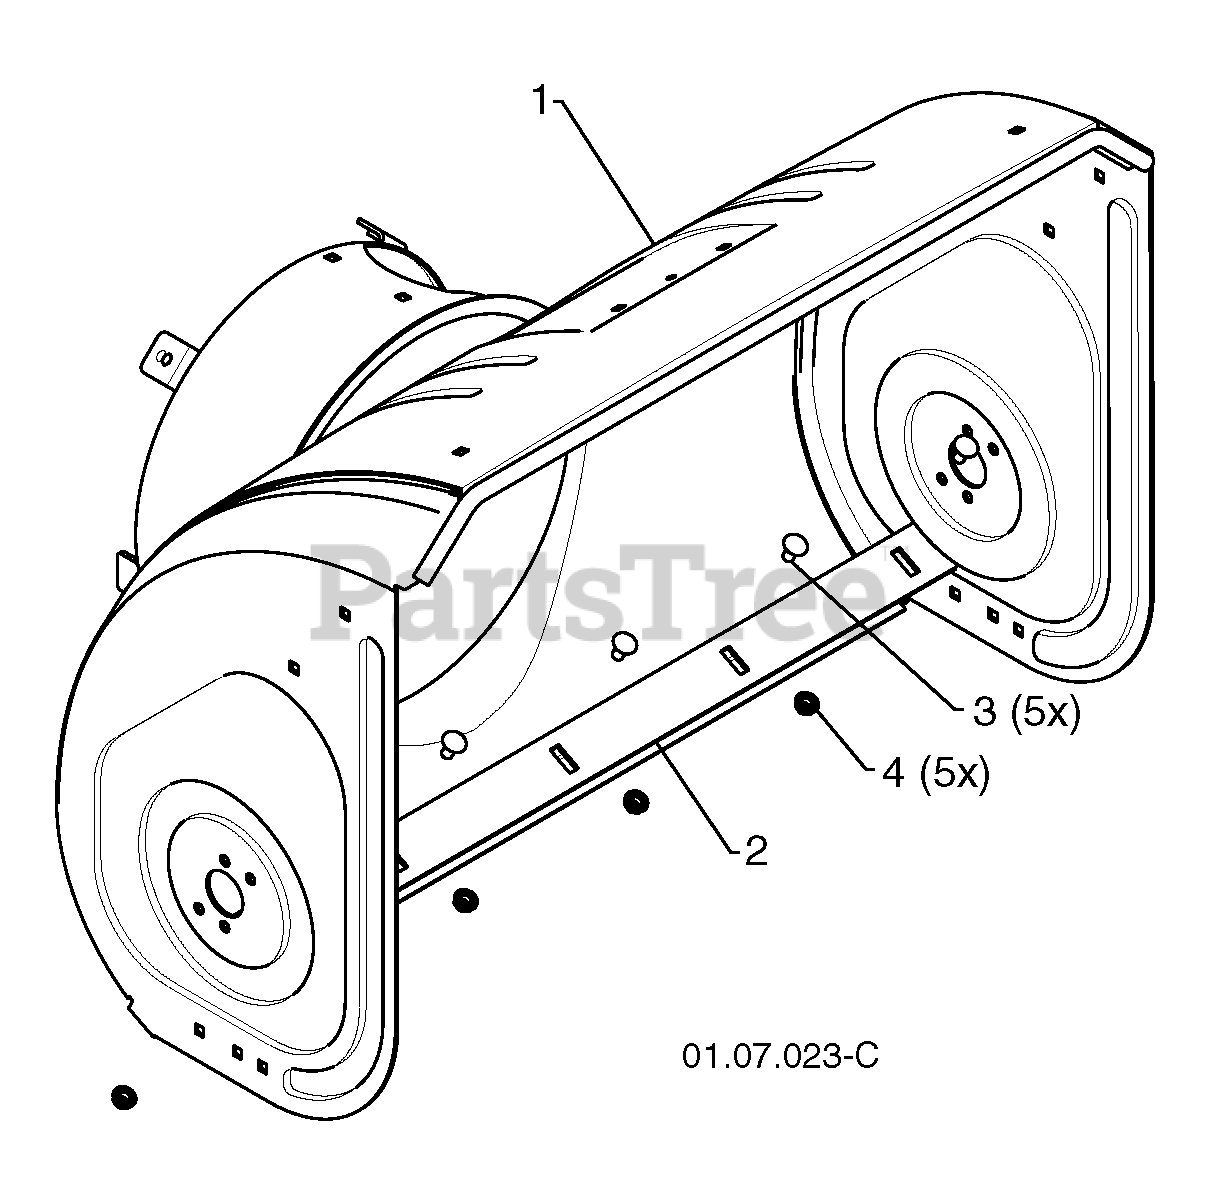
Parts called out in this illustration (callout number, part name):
1	HOUSING.AUG.WELDMENT.30.ORANGE
2	BAR, SCRAPER
3	BOLT
4	NUT.FLANGE.5/16
